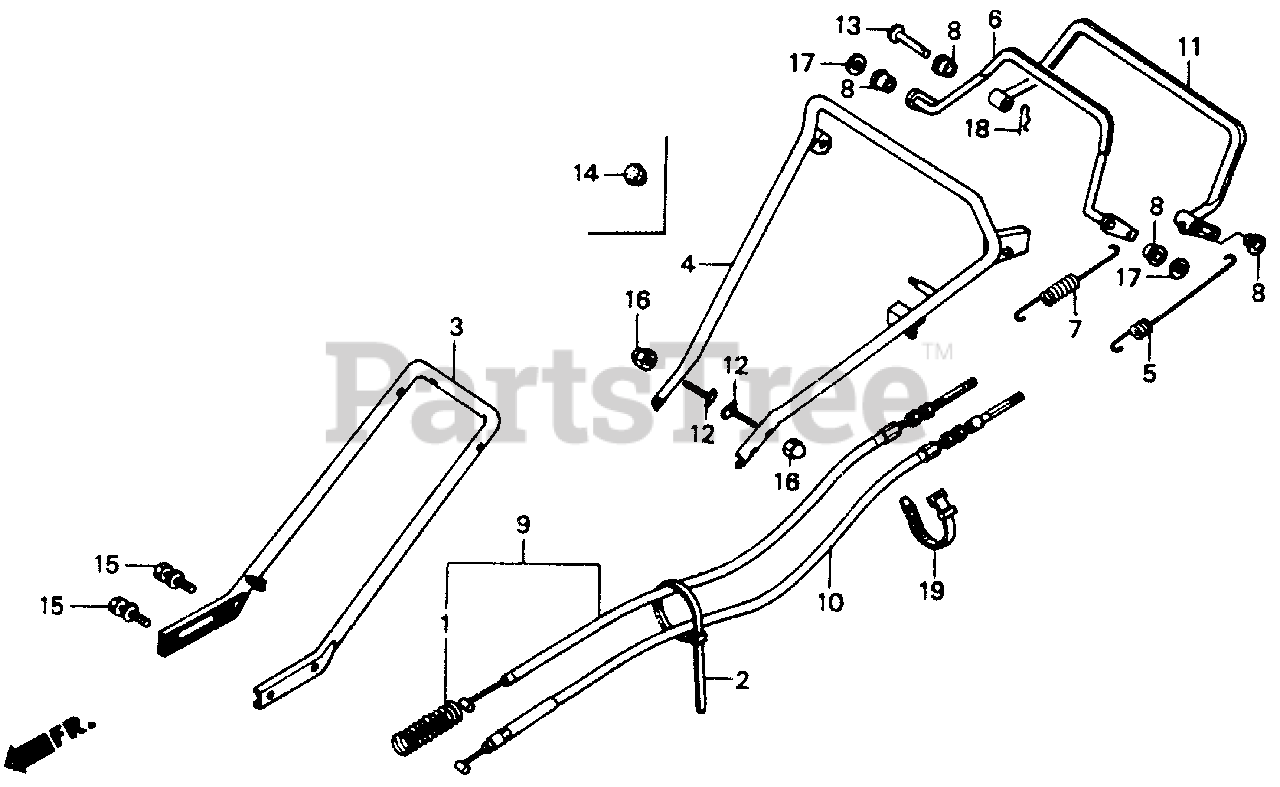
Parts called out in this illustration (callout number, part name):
1	SPRING, CLUTCH RETURN (NOT AVAILABLE)
2	TIE, CABLE (2.4X92) (NATURAL)
3	PIPE, HANDLE (LOWER)
4	HANDLEBAR (UPPER)
5	SPRING, BRAKE
6	LEVER, CLUTCH
7	SPRING, CLUTCH (NOT AVAILABLE)
8	BUSH, CLUTCH LEVER
9	CABLE, CLUTCH
10	CABLE, BRAKE
11	LEVER, BRAKE (NOT AVAILABLE)
12	BOLT, HANDLE HOLDER
13	PIN, BRAKE LEVER
14	GROMMET, TRUNK LID (NOT AVAILABLE)
15	BOLT-WASHER (8X28)
16	NUT, CAP (8MM)
17	WASHER, PLAIN (8MM)
18	PIN, LOCK (8MM)
19	TIE, CABLE
19	BAND B1, WIRE
